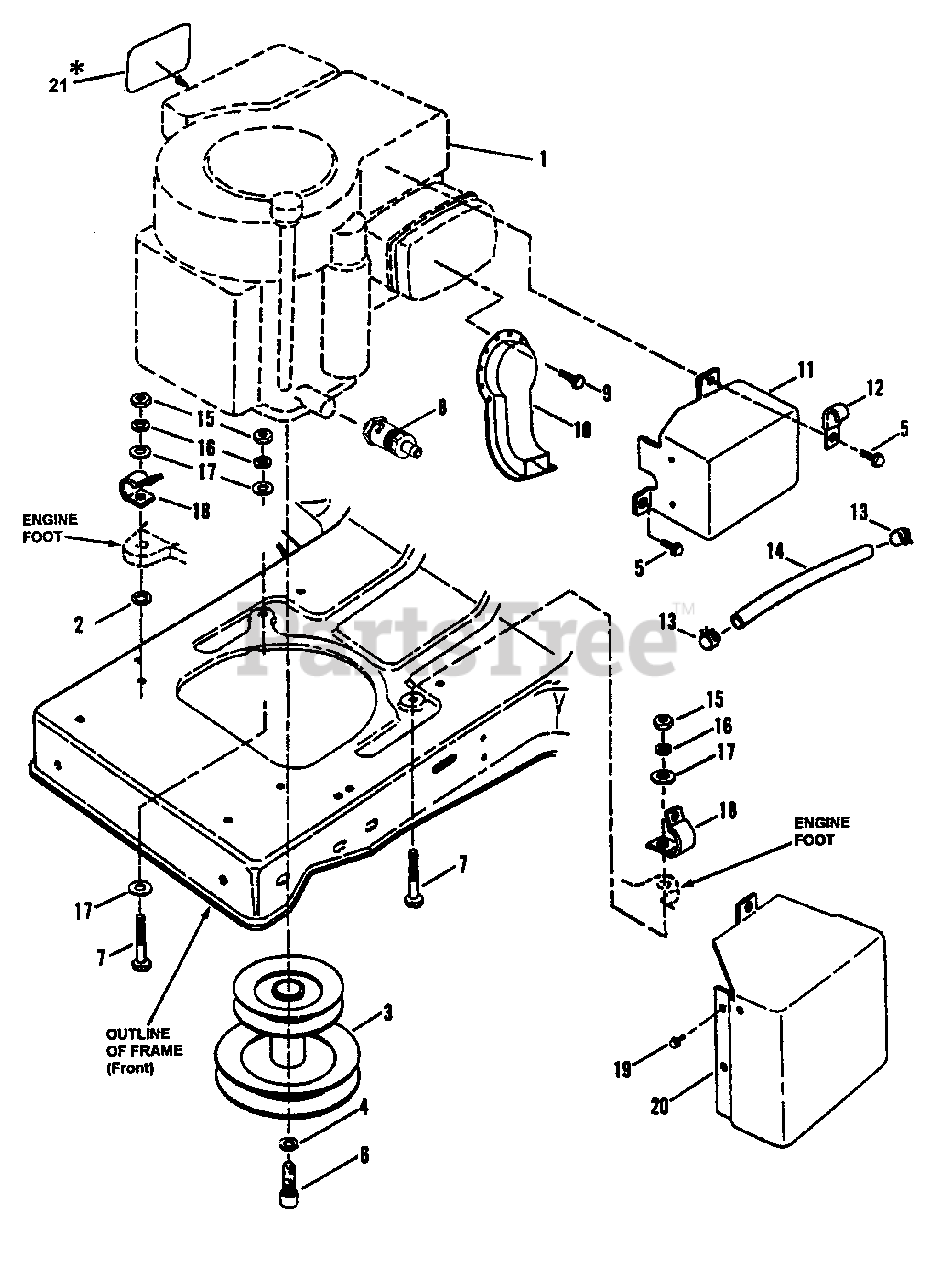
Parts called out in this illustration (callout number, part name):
2	WASHER, 5/16 Internal Tooth Lock
3	ASSEMBLY, Engine Pulley
4	WASHER, 7/16 Split Lock
5	BOLT, 1/4-20 x 1/2" Hex Flange Lock, Grade 5
6	SCREW, 7/16-20 x 1" Socket Head Cap
7	SCREW, 5/16-18 x 1-3/4" Hex Head Cap, Grade 5
8	ASSEMBLY, Oil Valve
9	SCREW, #8-18 x 1/2" Hex Head, Self-Tapping
10	EXTENSION, Muffler
11	HEAT SHIELD, Muffler
12	CLIP, "J" Type
13	CLAMP, Fuel Line
14	LINE, Fuel, 14" Long
15	NUT, 5/16-18 Hex, Grade 5
16	WASHER, 5/16 Split Lock
17	WASHER, 5/16 Flat
18	CLIP, Wiring Harness
19	SCREW, #10-24 x 5/8" Self-Tapping
20	HEAT SHIELD, Muffler
21	DECAL, Warning Speed Setting
